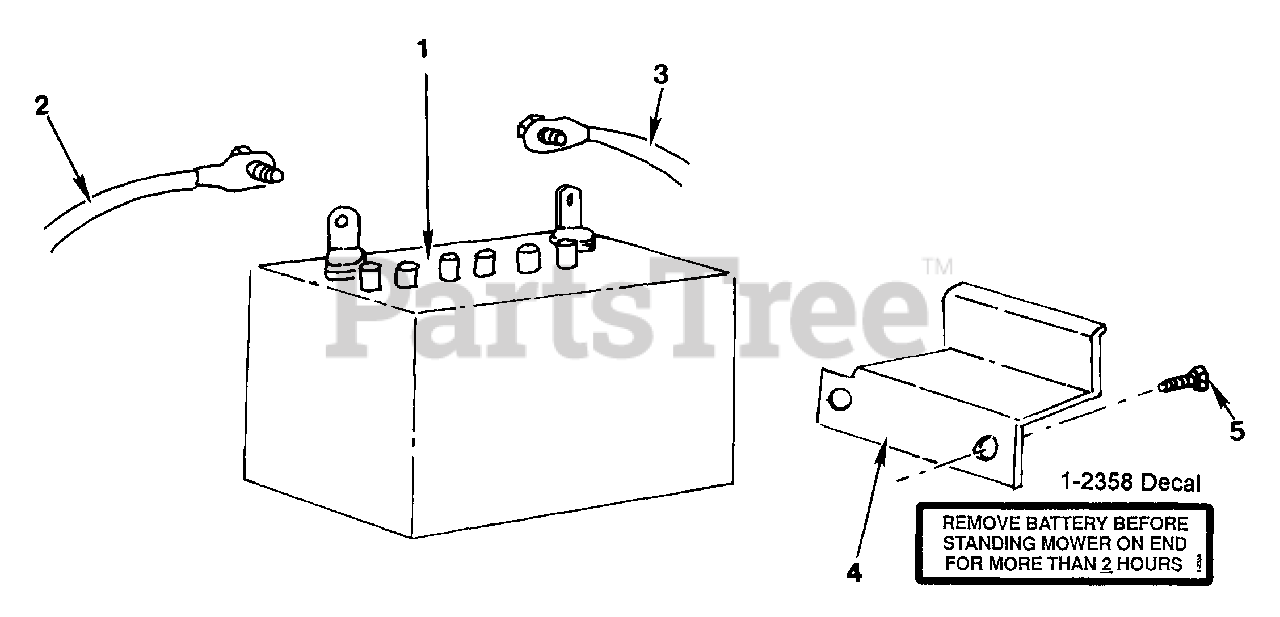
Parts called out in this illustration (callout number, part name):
1	KIT, Battery
2	Positive Wire Assembly
3	Negative Wire
4	Battery Clamp
5	5/16-18 x 5/8" Hex Head S.T. Scr.
12358	Decal
